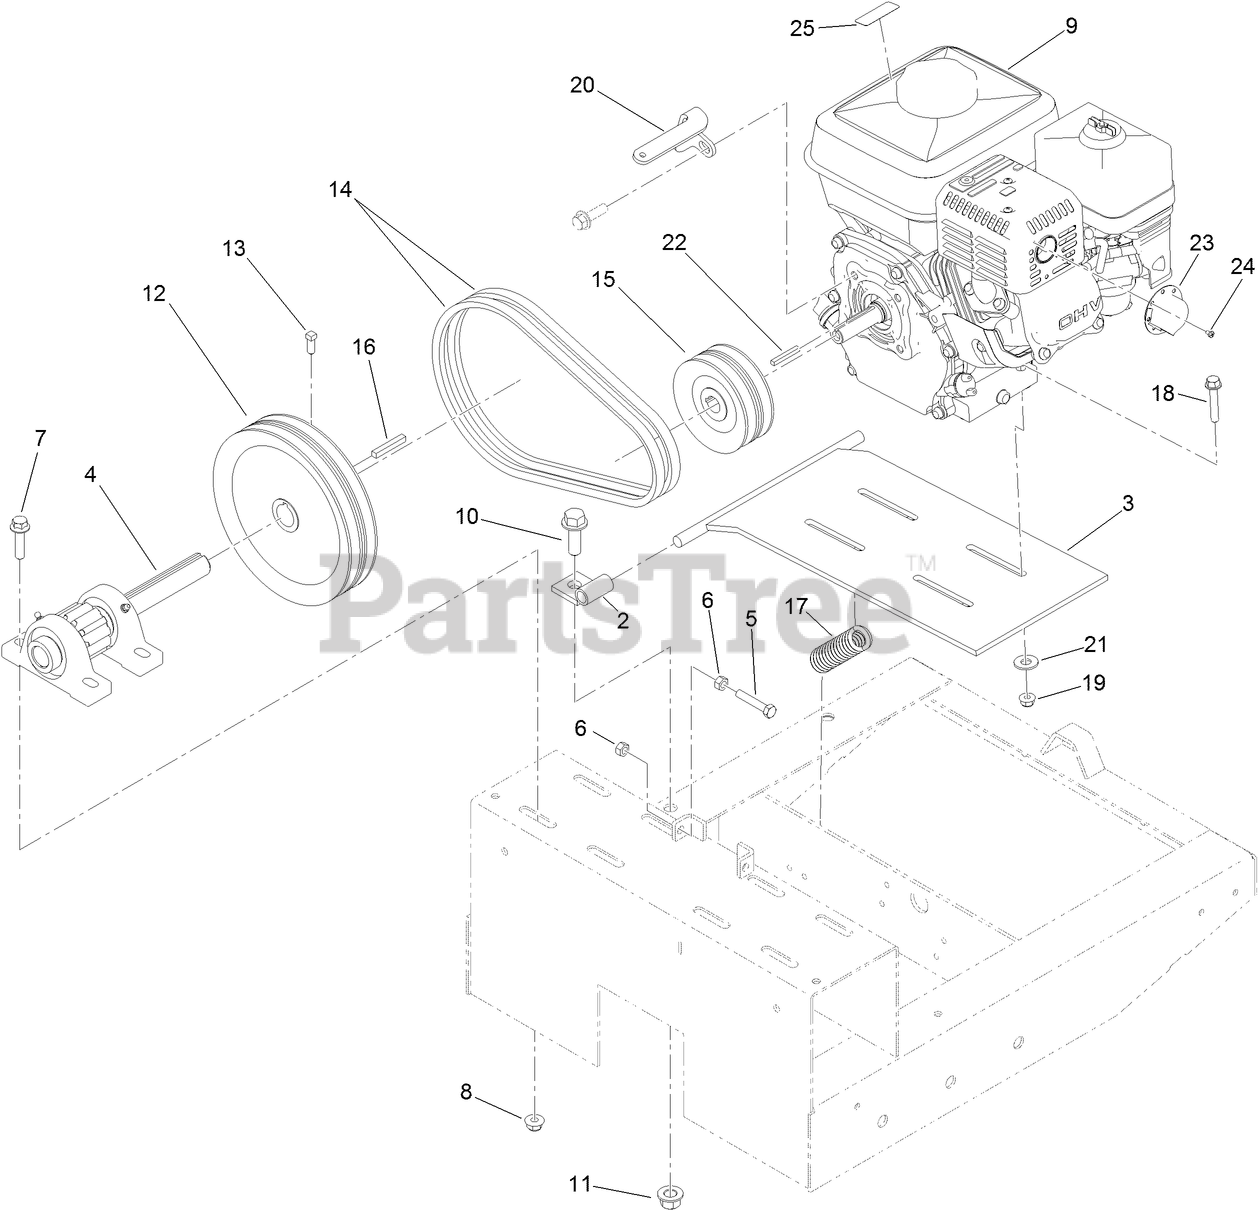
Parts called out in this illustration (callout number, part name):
2	MOUNT-MOTOR
3	BASE-MOTOR
4	PINION ASM
5	SCREW-HH
6	NUT-HEX
7	SCREW-HHF
8	NUT-HF, NI
9	ENGINE-HONDA, GX160
10	SCREW-HHF
11	NUT-LOCK
12	SHEAVE
13	SCREW-SET, SQH
14	BELT-V
15	SHEAVE
16	KEY-SQUARE
17	SPRING
18	SCREW-HWH
19	NUT-HF, NI
20	GUIDE-BELT
21	WASHER-FLAT
22	KEY-SQUARE
23	DEFLECTOR
24	SCREW-SELF TAPPING
25	DECAL-WARNING, ETHANOL
